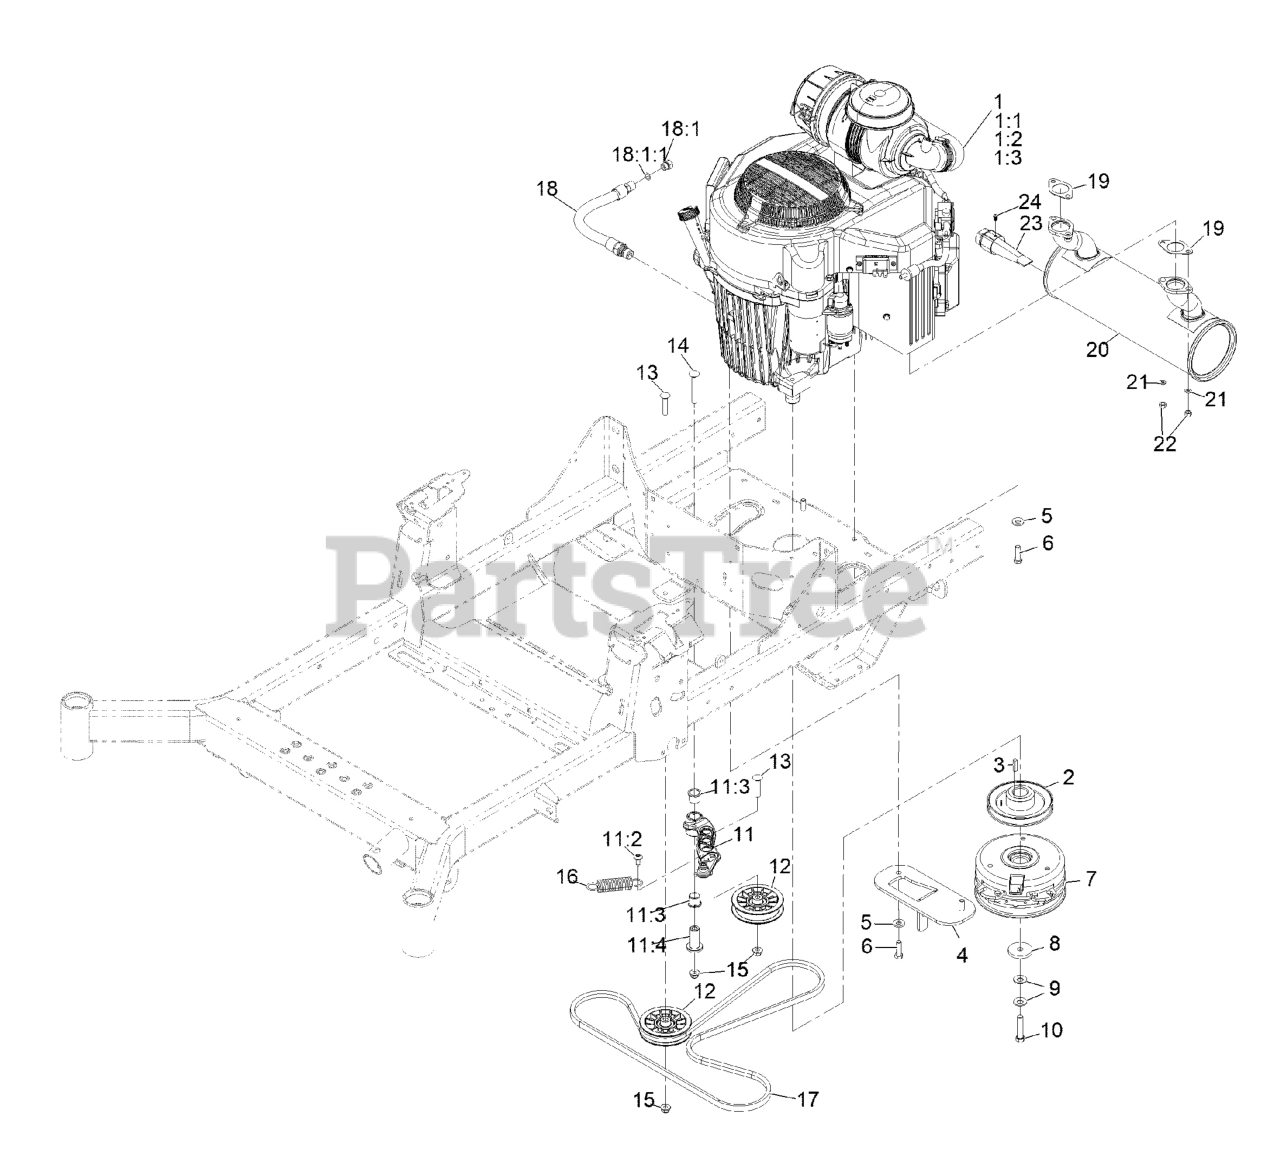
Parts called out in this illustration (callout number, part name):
1:1	Kawasaki 49065-7007 Engine Oil Filter
1:2	Kawasaki 11013-7044 Engine Air Filter
1:3	Kawasaki 11013-7045 Safety Filter
2	SHEAVE, ENGINE
4	Anchor-Clutch
5	WASHER-BELLEVILLE
6	SCREW-HH
7	CLUTCH-225 FTLBS
8	WASHER-CLUTCH
9	WASHER-SPRING
10	SCREW-HH W/LOCTITE
11	ASM, PUMP IDLER
11:2	SCREW, TAPTITE
11:3	BUSHING, IGUS
11:4	Spacer, Idler Pivot
12	PULLEY-FLAT IDLER
13	SCREW-CARR
14	SCREW-CARR
15	NUT-HF, NI
16	SPRING-EXTENSION
17	BELT-V
18	ENGINE OIL DRAIN HOSE ASM
18:1	PLUG-HH
18:1:1	O-RING
19	GASKET, EXHAUST
20	MUFFLER, KAWASAKI
21	WASHER-LOCK
23	Spark Arrestor, 1.5"
24	Screw-Ground
